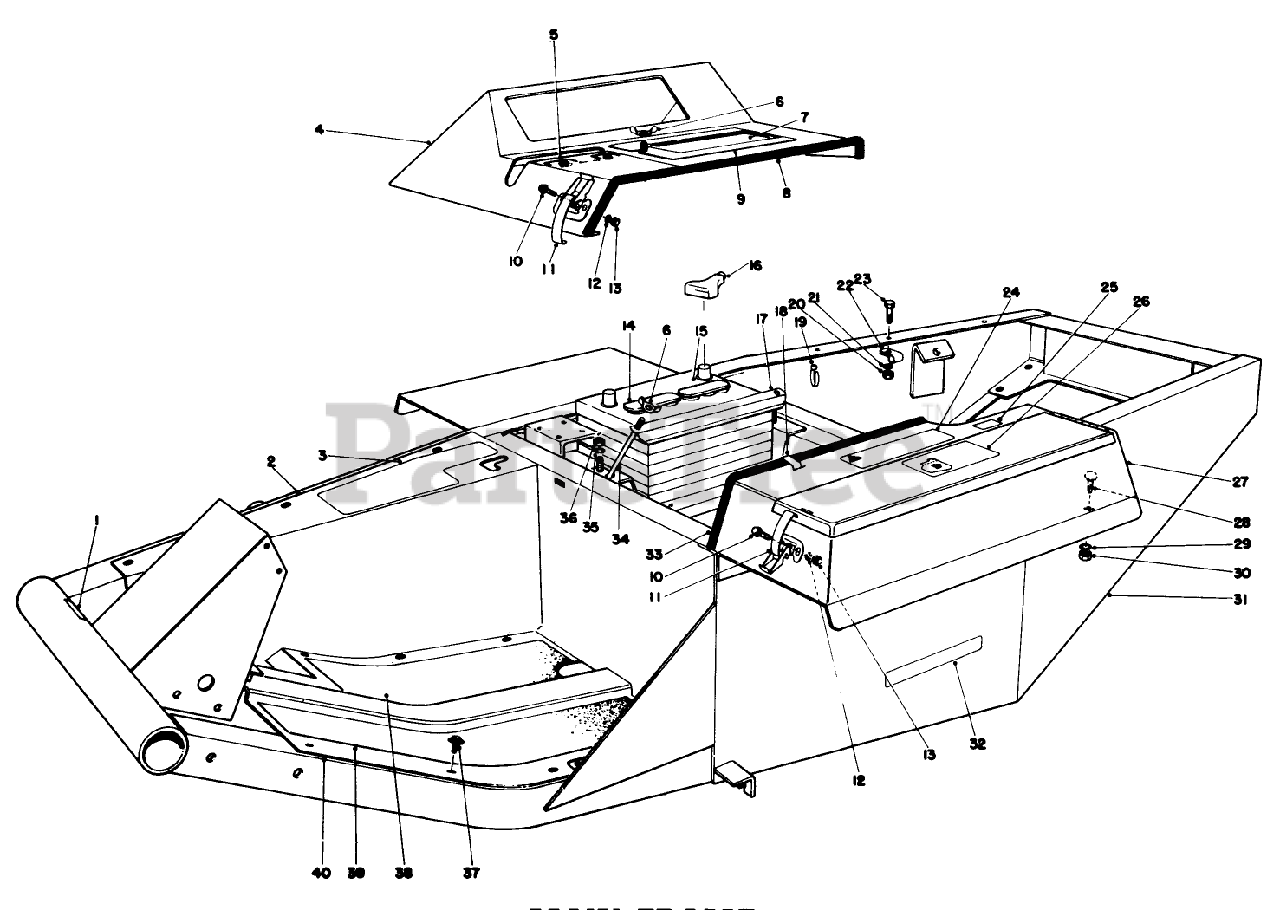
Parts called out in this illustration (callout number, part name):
1	DECAL-PEDAL, TRACTION
2	Footrest
3	Decal Caution
4	Cover-Instrument
5	DECAL-PTO
6	NUT-WING
7	Decal Starting Instructions
8	TRIM-COVER, INSTRUMENT
9	Cover Battery Access
10	SCREW-SHWH
11	CLAMP-SLOTTED
12	WASHER-LOCK
13	NUT-HEX
14	PUSH-ON BATTERY CAP
15	Battery (Incl. Ref. #14)
16	BOOT-CABLE, BATTERY
17	Battery Hold Down
18	TINNERMAN CLIP
19	TIE-CABLE
20	NUT-HEX
21	WASHER-LOCK
22	CLAMP-R
23	SCREW-HH
24	Decal Caution
25	DECAL GAS
26	DECAL-REFUELING
27	Box-Tool
28	SCREW-CARR
29	WASHER-LOCK
30	NUT-HEX
31	Frame
32	Decal Torque
33	TRIM-BOX, TOOL
34	STUD-HOLDDOWN, BATTERY
35	WASHER-LOCK
36	NUT-HEX
37	SCREW-HWH
38	PAD-FLOOR PLATE, RH
39	PAD-PLATE FLOOR, LH
40	Floor Plate
